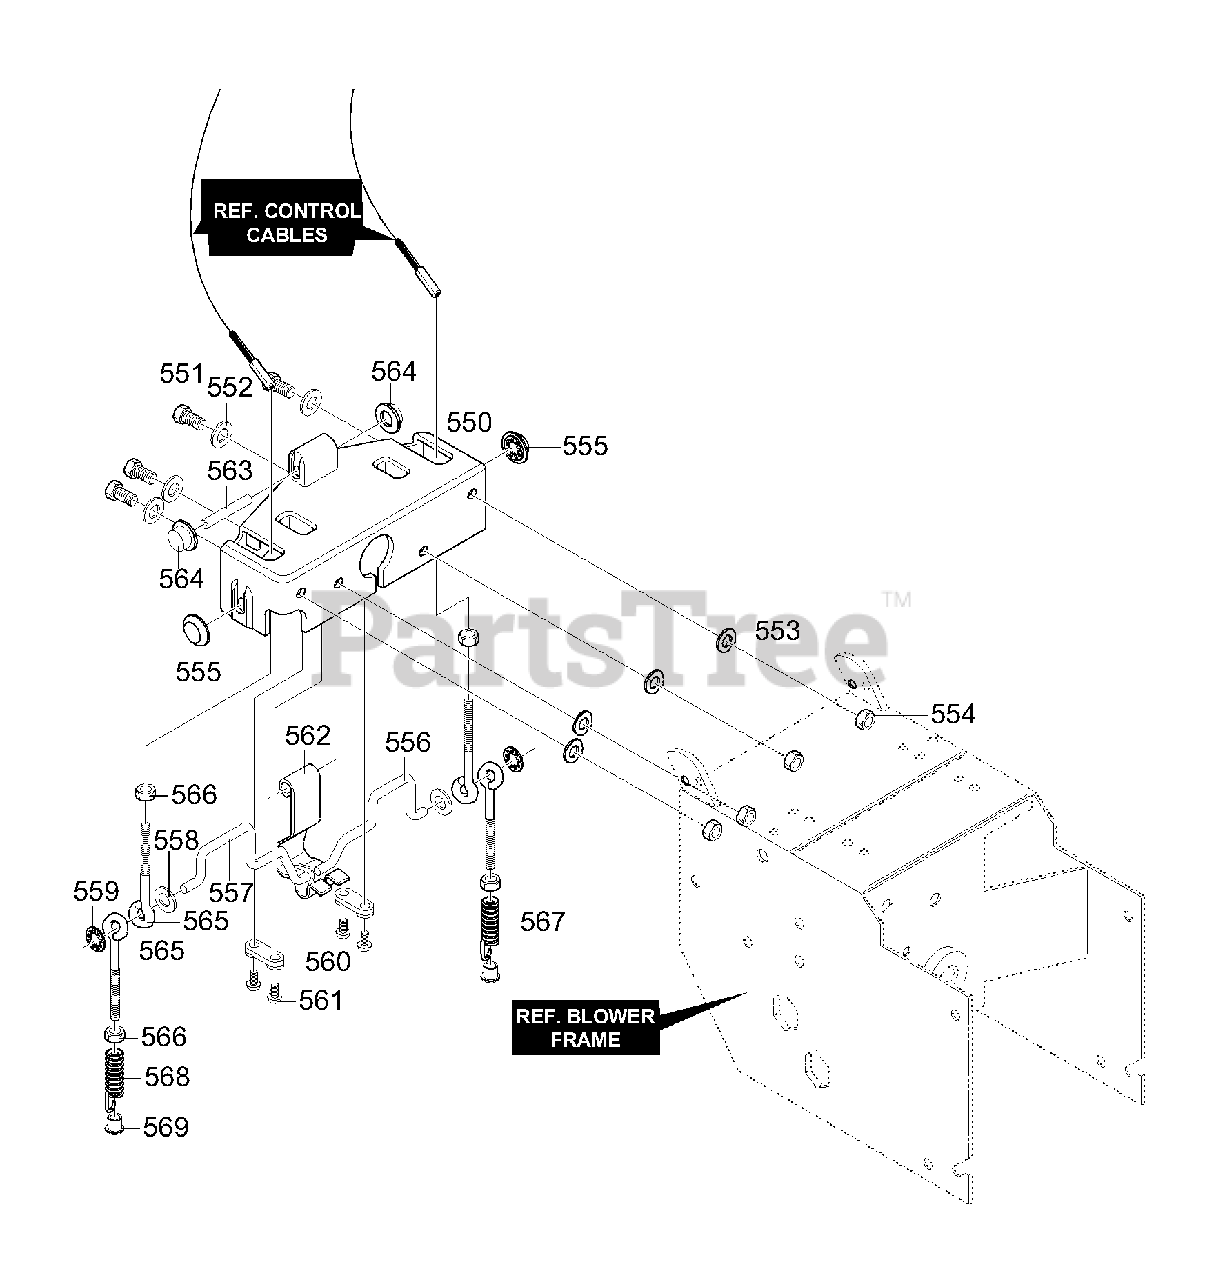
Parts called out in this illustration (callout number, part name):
550	HOUSING, SGL HAND CONTROL
551	SCREW, 5/16-18X.75
552	FLATWASHER, .344X.69X.065
553	WASHER, HVSPTLK .328X.60X.09
554	NUT, 5/16-18 REGHEX
555	NUT, PUSH ON CAP
556	CAM/LATCH, LH SHC
557	CAM/LATCH, RH SHC
558	FLATWASHER, .344X.69X.065
559	RING, RETEX
560	CLAMP, SHC CAM FRAME MTD
561	SCREW #8X.75 PANTAPPLAST
563	PIN, SPRING PIVOT
564	NUT, PUSH ON 3/8"
565	BOLT, EYE 10-24X2.50 W 3/8
566	NUT, #10-24 REGHEX
567	SPRING, DRIVE CLUTCH 2.75
568	SPRING, AUGER CLUTCH 2.38
569	NUT, 10-24 T
